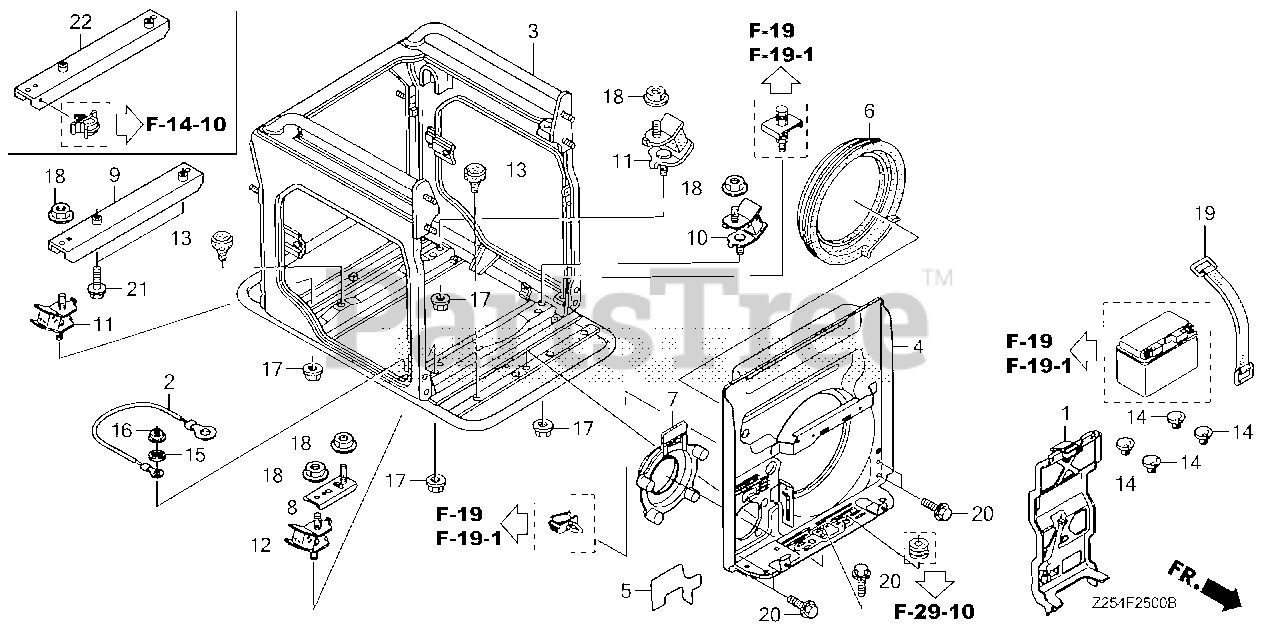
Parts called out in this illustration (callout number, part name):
1	BRACKET, WIRE HARNESS CLIP
2	CABLE, SUB-GROUND
3	FRAME, GENERATOR *NH105* (MAT BLACK)
4	FRAME, FR.
5	SEAL, FR. FRAME (NOT AVAILABLE)
5	SEAL, FR. FRAME
6	RUBBER A, SEPARATOR SEAL
7	RUBBER B, SEPARATOR SEAL
8	BRACKET, FR. ENGINE MOUNT *NH105* (MAT BLACK)
10	RUBBER (LOWER)
11	RUBBER (LOWER)
12	RUBBER, L. (LOWER)
13	RUBBER, STOPPER
14	RUBBER, BATTERY BOX
15	WASHER, LOCK (6MM)
16	NUT, FLANGE (6MM)
17	NUT, FLANGE (8MM)
18	NUT, FLANGE (10MM)
19	BAND F, BATTERY (155MM)
20	BOLT, FLANGE (8X12)
21	BOLT, FLANGE (8X30)
22	BRACKET, RR. ENGINE MOUNTING
